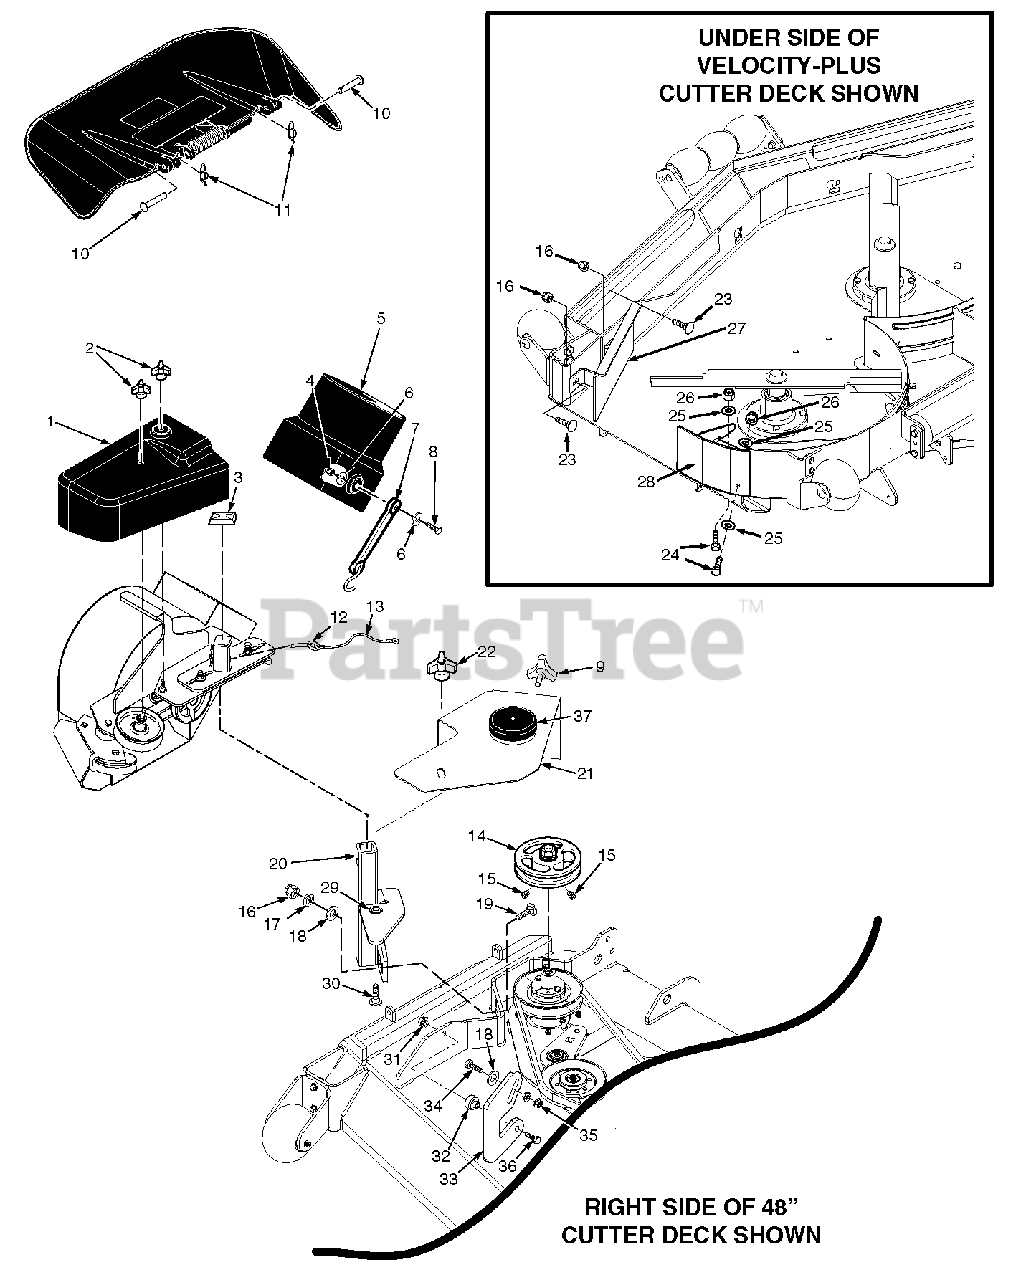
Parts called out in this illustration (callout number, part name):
1	Belt Cover, 48"
1	Belt Cover, 52"
2	Wingnut, Plastic 3/8" Small
3	Cap, Square Vinyl
4	Nut, Elastic Stop 1/4-20
5	Adapter, Blower GC-STC,
6	Flatwasher, 1/4-.312 x .750 x .065
7	Rubber Strap 7-3/4"
8	Bolt, Hex Head 1/4-20 x 1-1/4"
9	Knob W/Stud, 3/8-16 x 1-1/4"
10	Clevis Pin, 5/16 x 1-1/2"
11	Pin, Rue Cotter 5/16 Dia.
12	Pin, Ring 1/2 x 2-1/4"
13	Lanyard
14	Pulley, 4.0" Dia. 1.125 Bore
15	Setscrew, 5/16-18 x 3/8"
16	Nut, Elastic Stop 3/8-16
17	Lockwasher, 3/8"
18	Flatwasher, 3/8-.391 x .938 x .105
19	Bolt, Carr. 3/8-16 x 1-1/4"
20	Mounting Post Weldment, Blower
21	Belt Cover Assembly, w/Cap - 48"
21	Belt Cover Assembly, w/Cap - 52"
22	Wing Nut, 3/8 Plastic - Small
23	Bolt, Carriage 3/8-16 x 1"
24	Bolt, Hex Head 5/16-18 x 1"
25	Flatwasher, 5/16-.375 x .875 x .083
26	Nut, Elastic Stop 5/16-18
27	Baffle Weldment 48 / 52
28	Baffle, Turbo 48" Deck
28	Baffle, Turbo 52" Deck
29	Nut, Push-On 3/8 Thread
30	Bolt, Carriage 3/8-16 x 1-1/4"
31	Nut, Serrated Flange 3/8-16
32	Sleeve
33	Bracket
34	Bolt, Hex Head 3/8-16 x 1-.40"
35	Nut, Serrated Flange 3/8-16
36	Bolt, Hex Head 3/8-16 x 1-3/4"
37	Cap, Spindle
